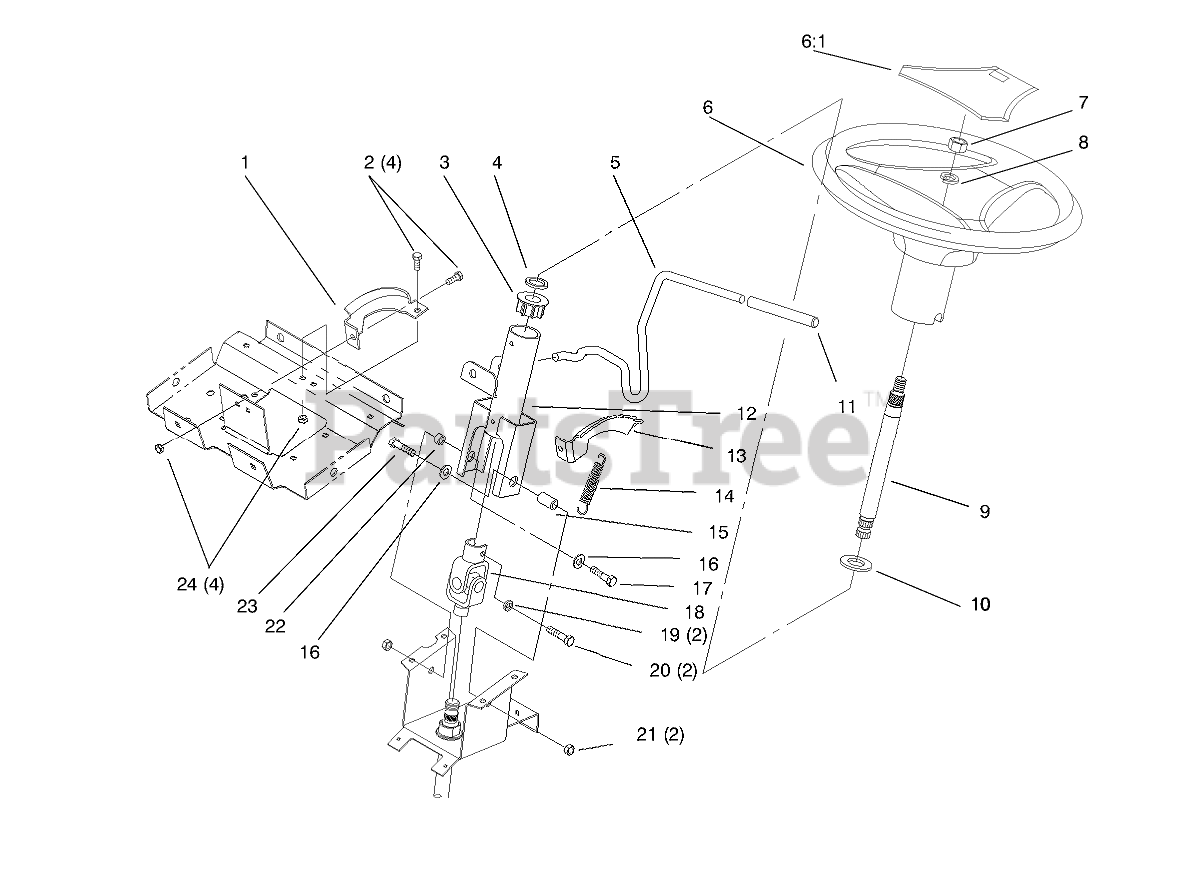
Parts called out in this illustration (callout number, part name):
1	BRACKET-SUPPORT, COLUMN
2	SCREW-HH
3	BUSHING-STEERING, UPPER
4	WASHER-BOWED
5	LEVER-TILT
6	WHEEL - STEERING, TORO
6:1	COVER-WHEEL
7	NUT-HH
8	WASHER-LOCK
9	SHAFT-SHORT, STEERING
10	WASHER-FLAT
11	CAP-ROD, TILT
12	COLUMN ASM
13	BRACKET-DETENT
14	SPRING-EXTENSION
15	SPACER-YOKE
16	WASHER-PLAIN
17	SCREW-HH
18	U-JOINT, STEERING
19	WASHER-LOCK
20	SCREW-CAP, HH
21	NUT-LOCK, NI
22	SPACER-YOKE, RIGHT
23	SCREW-HH
24	NUT-HEX
